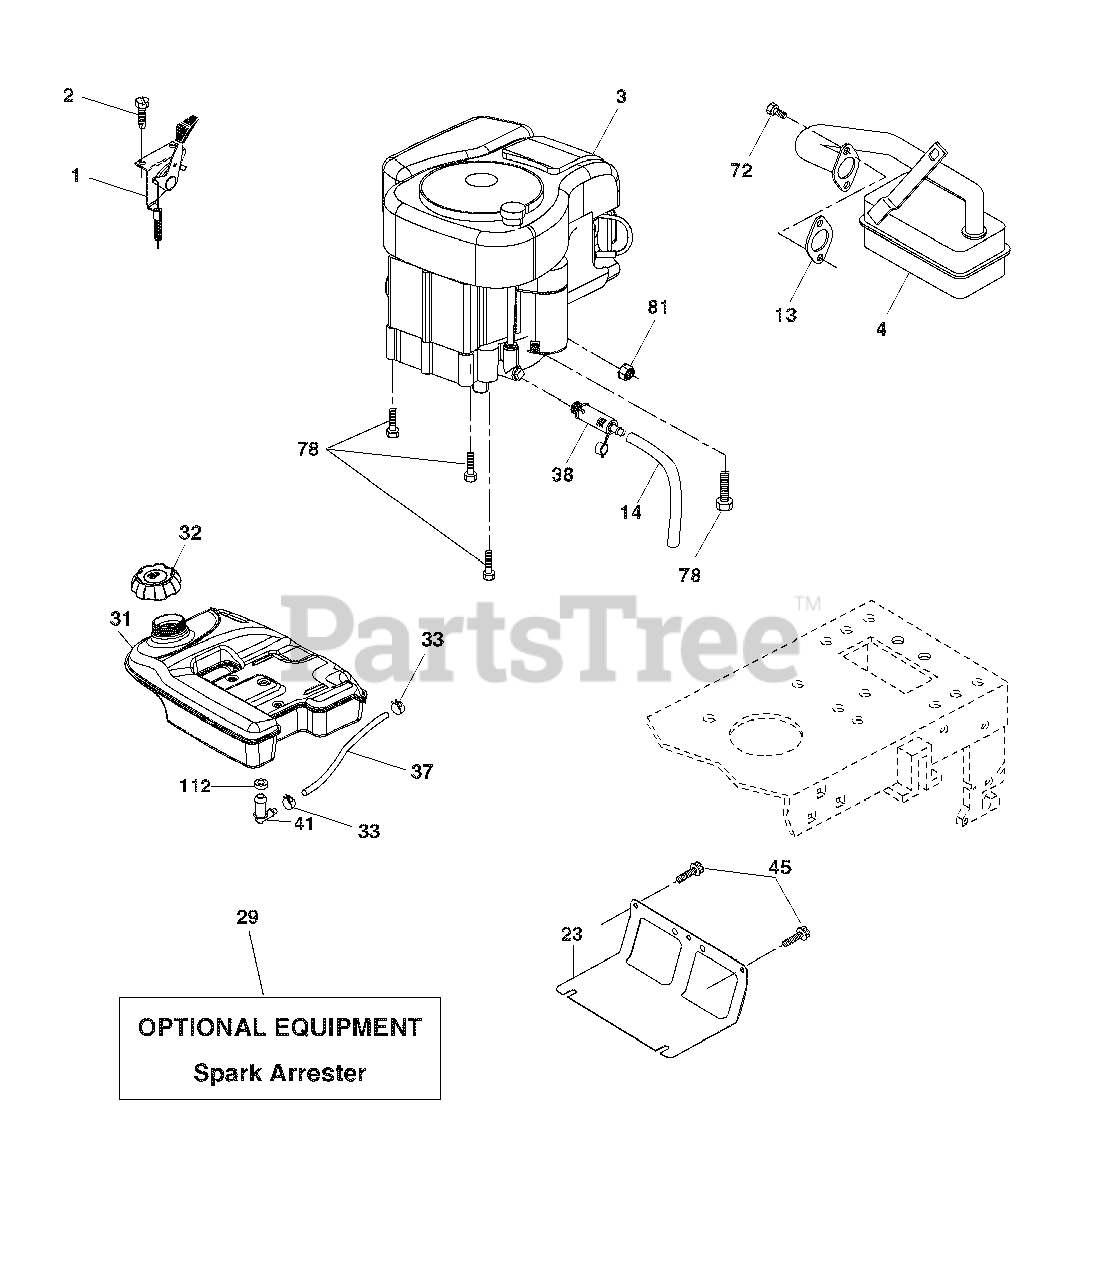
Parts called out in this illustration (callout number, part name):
1	Control, Throttle/Choke
2	Screw #10 x 0.750
13	Muffler Gasket
14	Tube Oil Drain
23	Shield, Browning/Debris Guard
29	Arrester, Spark
31	Tank, Fuel
32	Cap, Fuel
33	Clamp, Hose Blk
37	Line, Fuel
38	Plug Drain Oil Easy
41	Stem Tank Fuel
45	Screw Hex Wsh Thdrol 3/8-16 x 3/4
72	Screw 5/16-18 x .75
78	Screw 3/8-16 x 1-1/4
81	Nut Keps Hex 1/4-20 unc
112	Bushing
